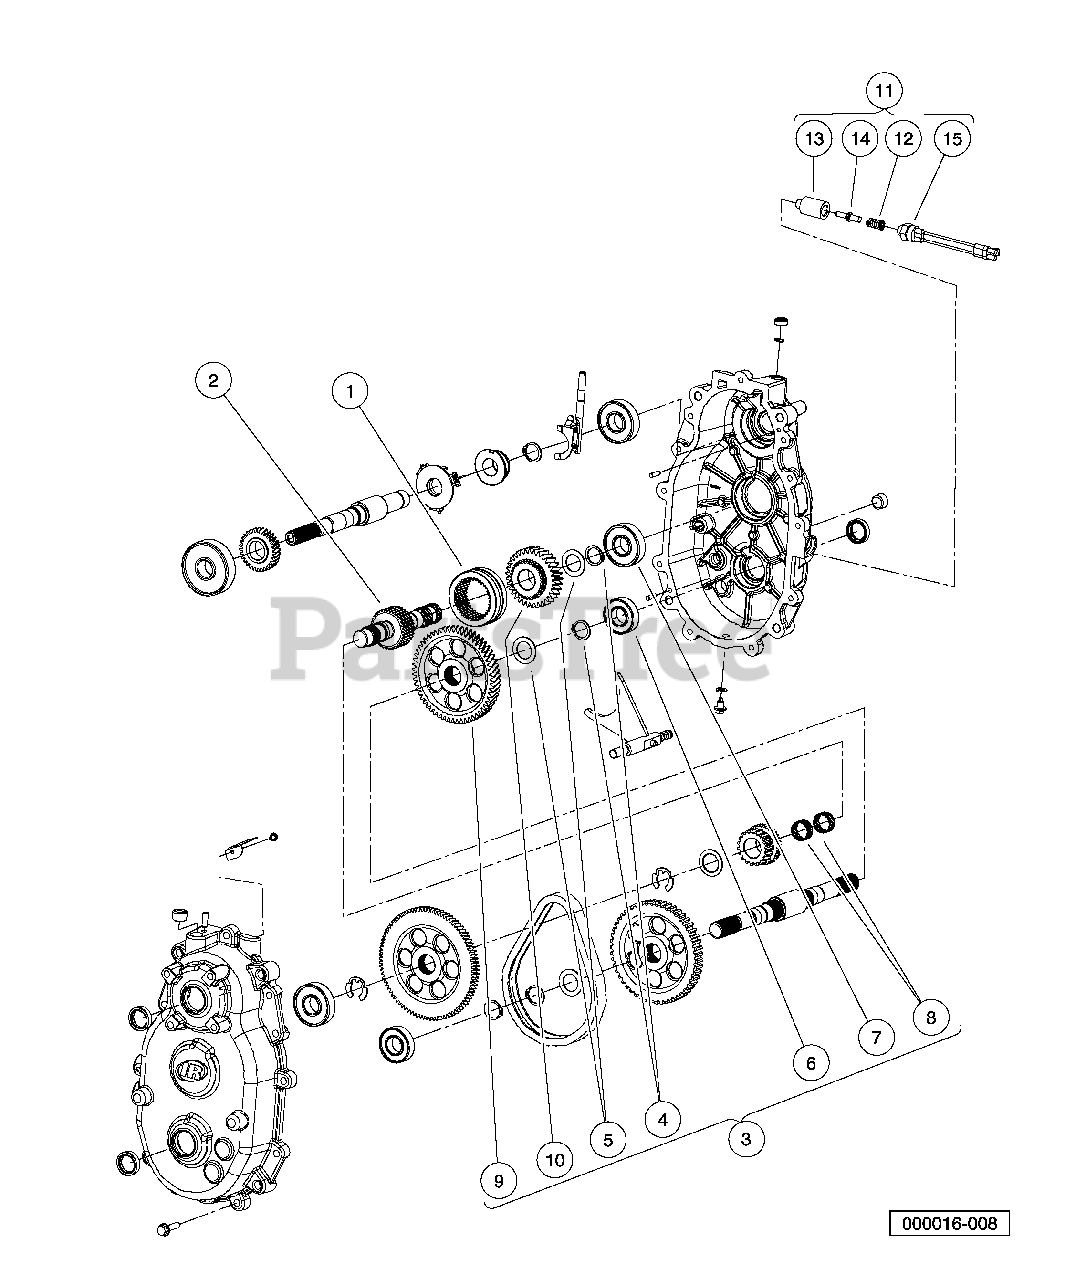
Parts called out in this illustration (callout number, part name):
1	Dog, Engagement
2	Shaft, Intermediate.
3	Kit, Forward Gear Repair
4	Ring, Retaining, Basic External
5	Washer, Thrust, 1.007 X .062
6	Bearing, Ball
7	Bearing, Ball
8	Bearing, Needle.
11	Kit, Neutral Switch Repair
13	Guide, Detent Bullet
14	Bullet, Detent
15	Switch, Indicator, Pollak
